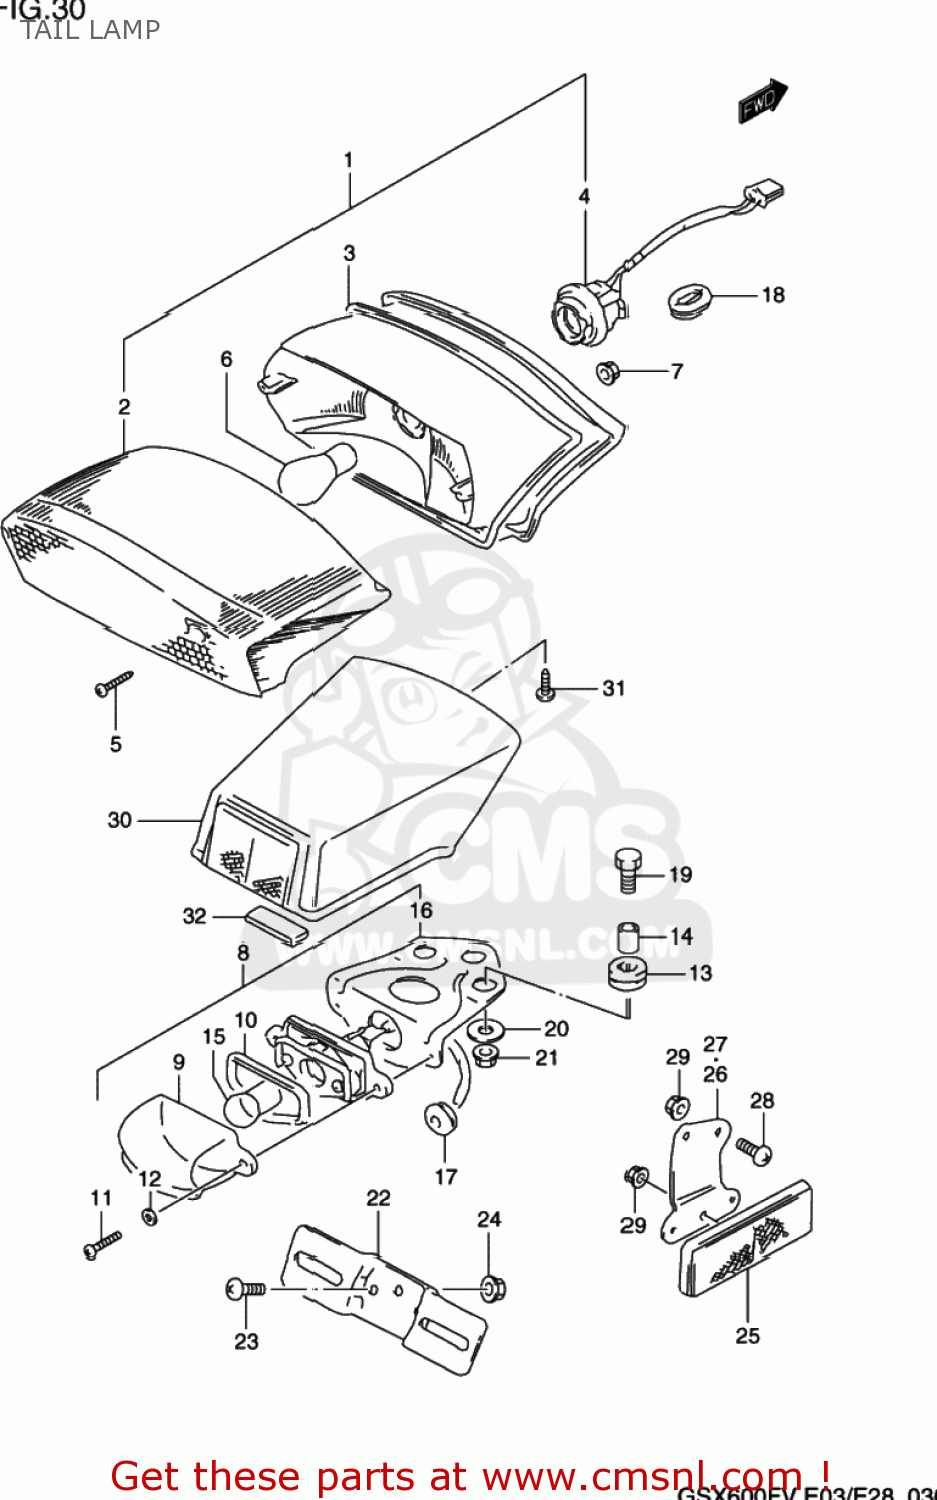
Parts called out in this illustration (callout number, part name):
1	LAMP ASSY,RR COMBINATION
2	LENS
3	GASKET (NAS)
4	SOCKET
5	SCREW
6	BULB(12V21/5W,BF141-49642A)
7	NUT
8	LAMP ASSY,LICENSE
9	LENS,LICENSE LAMP
10	GASKET,LICESE LAMP (NAS)
11	SCREW 4X16
12	WASHER
13	CUSHION,RR COMBINATION
14	SPACER
15	BULB(12V5W,BF150-40160A)
16	BRACKET
17	GROMMET
18	GROMMET
19	BOLT(6X20)
20	WASHER(6.5X20X1.2)
21	NUT
22	BRACKET,LICENSE PLATE
23	SCREW 6X16
24	NUT 6MM
25	REFLECTOR ASSY,RR
26	BRACKET,RR SIDE RR,R
27	BRACKET,RR SIDE RR,L
28	SCREW 5X12
29	NUT
30	COVER,LICENSE LAMP
31	SCREW
32	PROTECTOR,LICENSE LAMP
